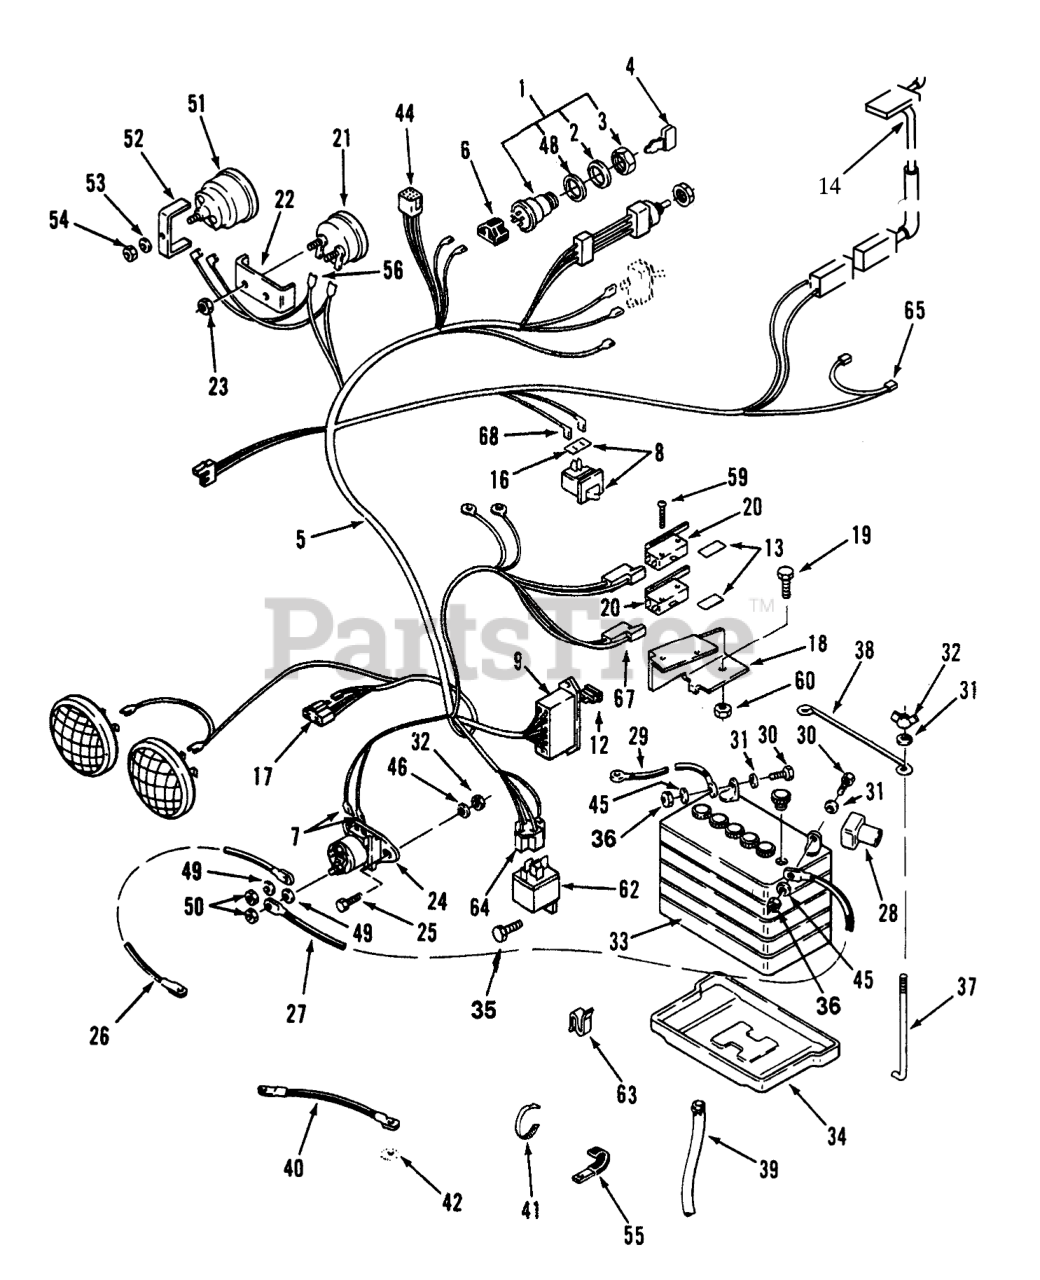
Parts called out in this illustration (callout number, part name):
1	KEY SWITCH ASM
2	LOCKWASHER
4	KEY-IGNITION
5	WIRING HARNESS & DIA
6	CONNECTOR BODY ELECT
7	TERMINAL 10
8	SWITCH INTERLOCK
9	FUSE-HOLDER 4 WAY
12	FUSE-BLADE, 15 AMP
13	BARRIER - SWITCH
14	SWITCH-SEAT
16	SHIELD-DIRT SPST
17	5-CONTACT CONN BODY
18	BRACKET-SWITCH
19	Bolt
20	SWITCH
21	VOLTMETER
22	CLAMP-MOUNTING
23	HEX NUT 10-32 E.S.
24	SOLENOID
25	Screw
26	ASSY WIRE
27	CABLE-BLACK
28	Boot
29	ASSY WIRE
30	SCREW-HH
31	WASHER-FLAT
32	Nut
33	Battery
34	TRAY-BATTERY
35	NUT-LOCK, INSERT
37	HOOK-BATTERY RETAIN
38	HOLDDOWN-BATTERY
39	TUBE-21" BATTERY DRAIN
40	WIRE GROUND
41	PLASTIC TIE
42	WASHER-LOCK, INTERNAL
44	Terminal
45	WASHER-LOCK
48	Washer
49	WASHER-LOCK
50	NUT-JAM
51	Meter-Hour (Incl. Ref. #52-54)
52	BRKT-GAUGE MOUNTING
53	Lockwasher
54	Hex Nut
55	CLIP
59	Screw
60	NUT HEX 4-40 ELAST
62	RELAY
63	CLIP-CABLE
64	TERMINAL 10
65	Sur-Plug
68	Terminal
